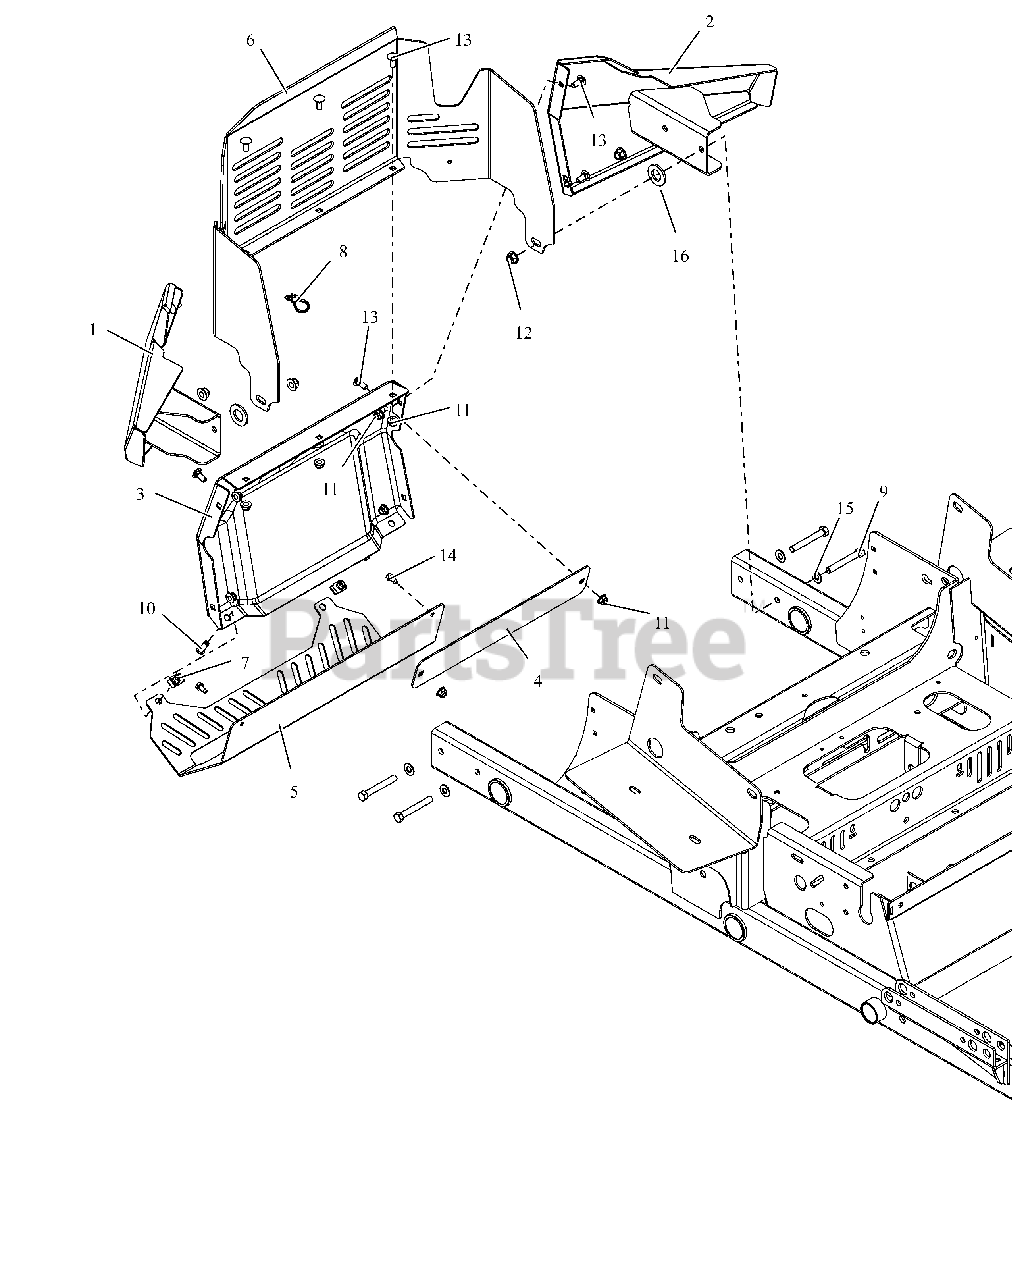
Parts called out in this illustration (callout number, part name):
1	WMT,RH REAR BMPR WING W/DECAL
2	WMT,LH REAR BMPR WING W/DECAL
3	PT200/400 REAR BUMPER - BLACK
4	BACKER PLATE - RED
5	PT200/400 MUFFLER GUARD - BLK
6	PT200 ENGINE GUARD - RED
7	NUT-CLIP RETAINER 5/16-18X.56
8	CABLE TIE W/ TREE (.25 HOLE)
9	BLT, HEX .38-16X2.75 G5 ZCC
10	BLT,SHCS-BTN .31-18X1.00 ZCC
11	NUT,NYL-FLG .31-18 GF ZCC
12	NUT,NYL-FLG .38-16 GF ZCC
13	BLT,RHSN .31-18X.75 G5 ZCC
14	SCR-TAP .25-20X.50 HWH ZCC
15	WSHR,FLT .406X.812X.065 ZCC
16	WSHR-FL-STL 0.812X1.469X0.134 ZCC
